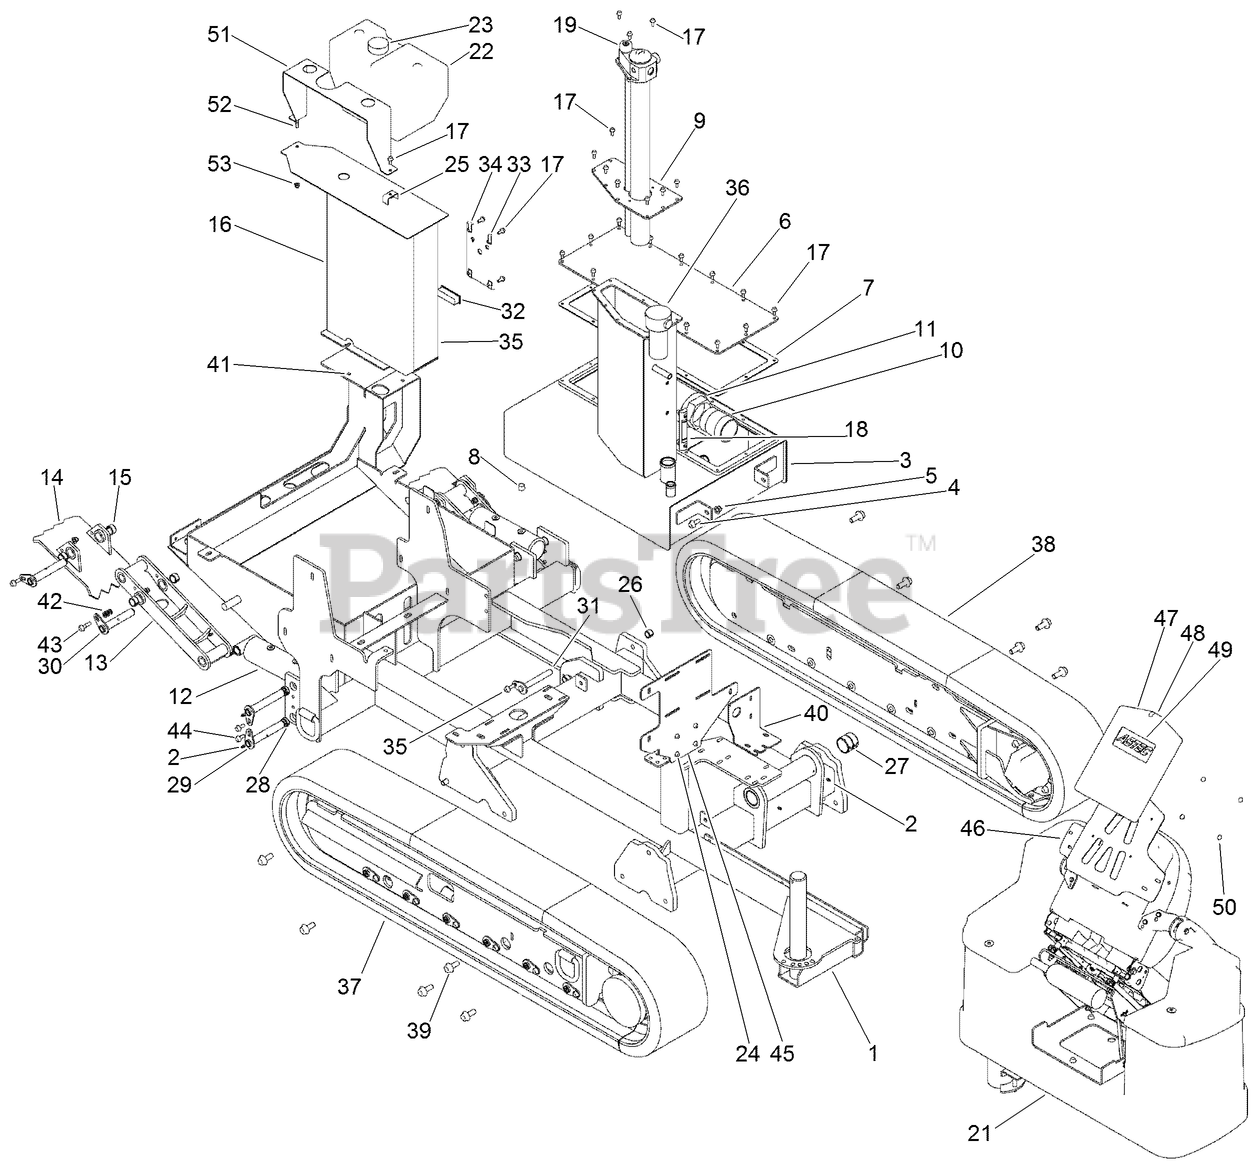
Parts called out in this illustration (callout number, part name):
1	FRAME - Main
2	FITTING-Lube 1/4-28 Tpr SAE-LT .54 Long
3	TANK - Hydraulic
4	SCREW, METRIC FLANGE w/BODY-M12 x 30
5	NUT-HHF, LOCK
6	PLATE - Hydraulic Tank Cover
7	GASKET-COVER LID, HYDRAULIC TANK
8	PLUG-PIPE, HEX SOCKET
9	PLATE - Hydraulic Tank Lid
10	NIPPLE-PIPE
11	STRAINER-SUCTION, 100 MESH
12	HYD CYLINDER ASM
13	WELDMENT - Stabilizer Leg
14	WELDMENT - Stabilizer Foot
15	BUSHING-SPRING
16	WELDMENT - Rear Controls Box
17	SCREW, METRIC FLANGE w/BODY - M8 x 20
18	GAUGE-SIGHT
19	FILTER ASM (HYDRAULIC TANK)
21	ASSEMBLY - Operators Console
22	BOTTLE - Mud Pump System Anti-Freeze
23	CAP - Anti-Freeze Bottle
24	SCREW-HH
25	NUT-TORQUE, PREVAILING
26	BUSHING-SPRING
27	BUSHING-SPRING
28	BUSHING-SPRING
29	PIN-FLAG
30	PIN-FLAG
31	PIN-FLAGGED
32	LATCH-TRIGGER, RAISED (W/LOCK)
34	PLATE - Rear Controls Panel
35	SCREW-HH
36	FILTER-HYD, 350PSI (6 MICRON)
37	ASSEMBLY - Track RH
38	ASSEMBLY - Track LH
39	SCREW-HHF
40	PLATE - Mount
41	NUT-FLANGE, NYLOCK
42	WASHER - 0.406 x 0.750 x 0.119 in CST ZND
43	SCREW-HHF
44	SCREW-FLANGE
45	PLATE - Fuse Box Mount
46	PLATE - Operators Manual Case Mounting
47	HOLDER-MANUAL, OPERATOR
48	LANYARD
49	POST-MANUAL
51	BRACKET - Anti-Freeze Bottle
52	SCREW, METRIC FLANGE w/BODY - M8 x 45
53	NUT, METRIC HEX FLANGE - M8, Zinc
